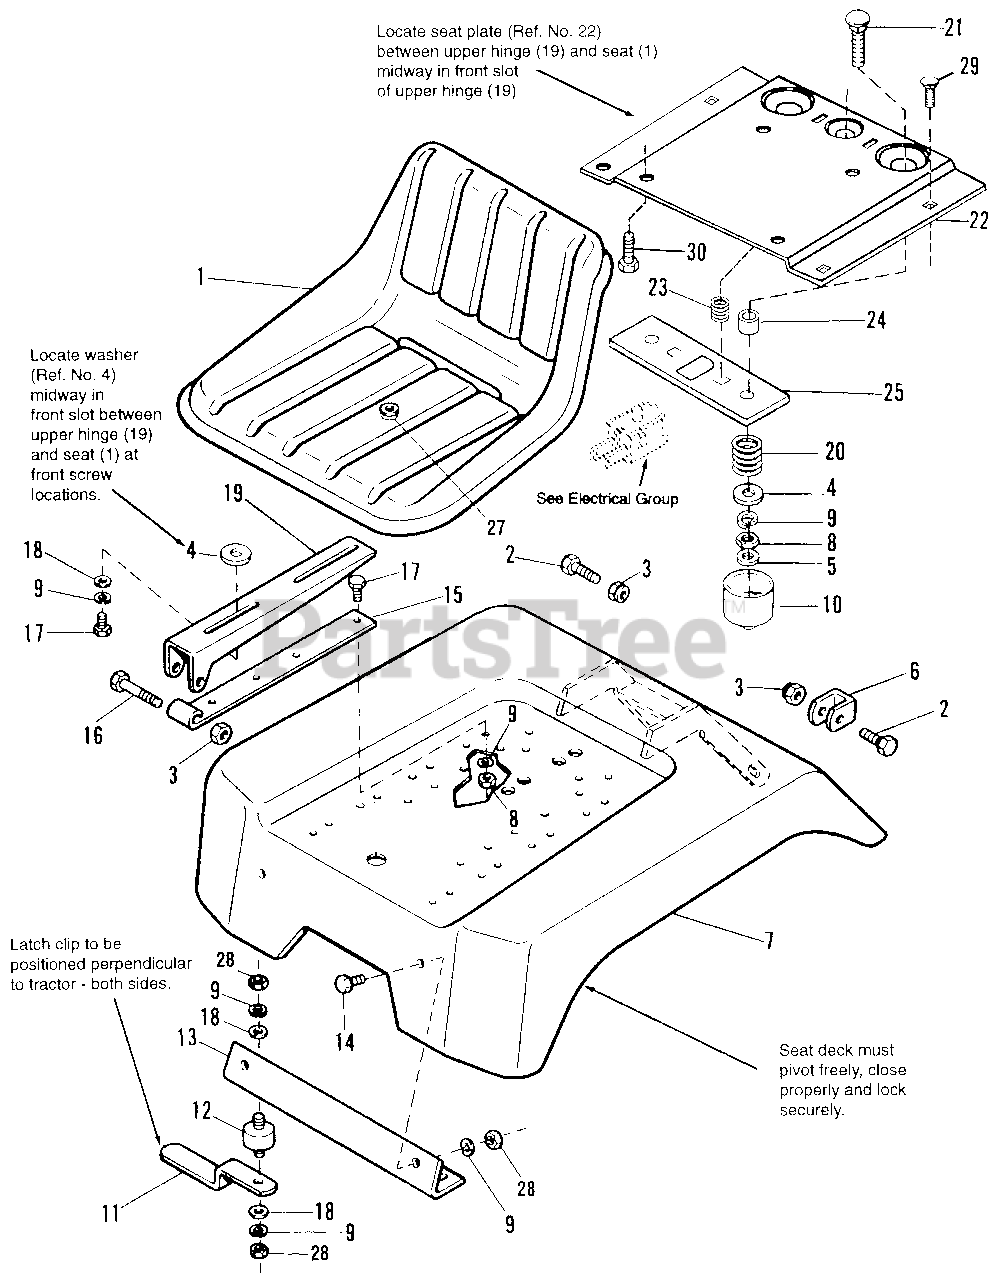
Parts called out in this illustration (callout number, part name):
1	SEAT ASSY. (Incl. Ref. No. 26)
2	CAPSCREW, Hex Hd,3/8-16x1-1/4
3	LOCKNUT, Hex, 3/8-16
6	STOP, Seat Deck
7	DECK ASSY., Seat
8	NUT, Hex, Fu11,5/16-18
9	LOCKWASHER, 5/16
10	COVER, Spring
12	CONNECTOR, Cushion
13	BRACKET, Seat Deck, Front
14	CAPSCREW, Hex Hd, 5/16-18x5/8
15	HINGE, Lower
16	CAPSCREW, Hex Hd., 3/8-16 x 2
17	CAPSCREW, Hex Hd., 5/16-18x3/4
18	WASHER, Plain, 5/16
19	HINGE, Upper
21	CARRIAGE BOLT, 5/16-18x 1-1/2
22	PLATE, Seat
25	PLATE, Switch
26	COVER, Seat
28	NUT, Hex, Lock, Esna, 5/16-18
29	CARRIAGE BOLT, 5/16-18 x 3/4
30	SCREW, Hex, Whizlock, 5/16-18 x 5/8
